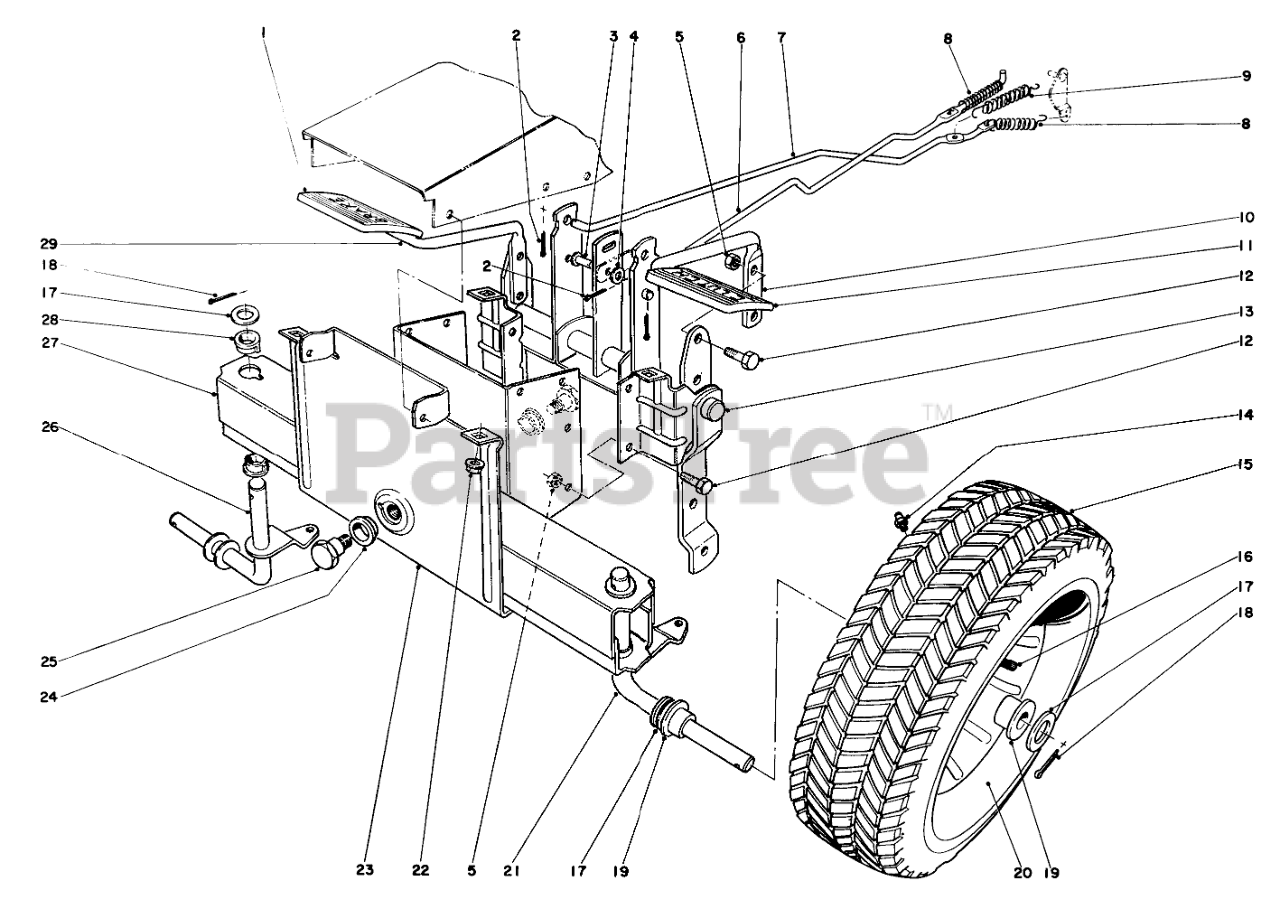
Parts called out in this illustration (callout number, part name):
1	PAD-BRAKE
2	PIN-COTTER
3	PIN-CLEVIS
4	WASHER-PLAIN
5	Nut
6	Clutch Rod
7	Brake Rod
8	Spring
9	Spring, Brake
10	Clutch Pedal
11	CLUTCH PAD
12	SCREW-HH
13	Control Shaft W.A.
14	FITTING-GREASE
16	STEM-VALVE
17	WASHER-FLAT
18	PIN-COTTER
19	BUSHING
21	Spindle L.H.
22	NUT-HF
23	Frame Lower Front
24	Bushing
26	Spindle R.H.
27	Front Axle
28	Bushing
29	Brake Pedal
